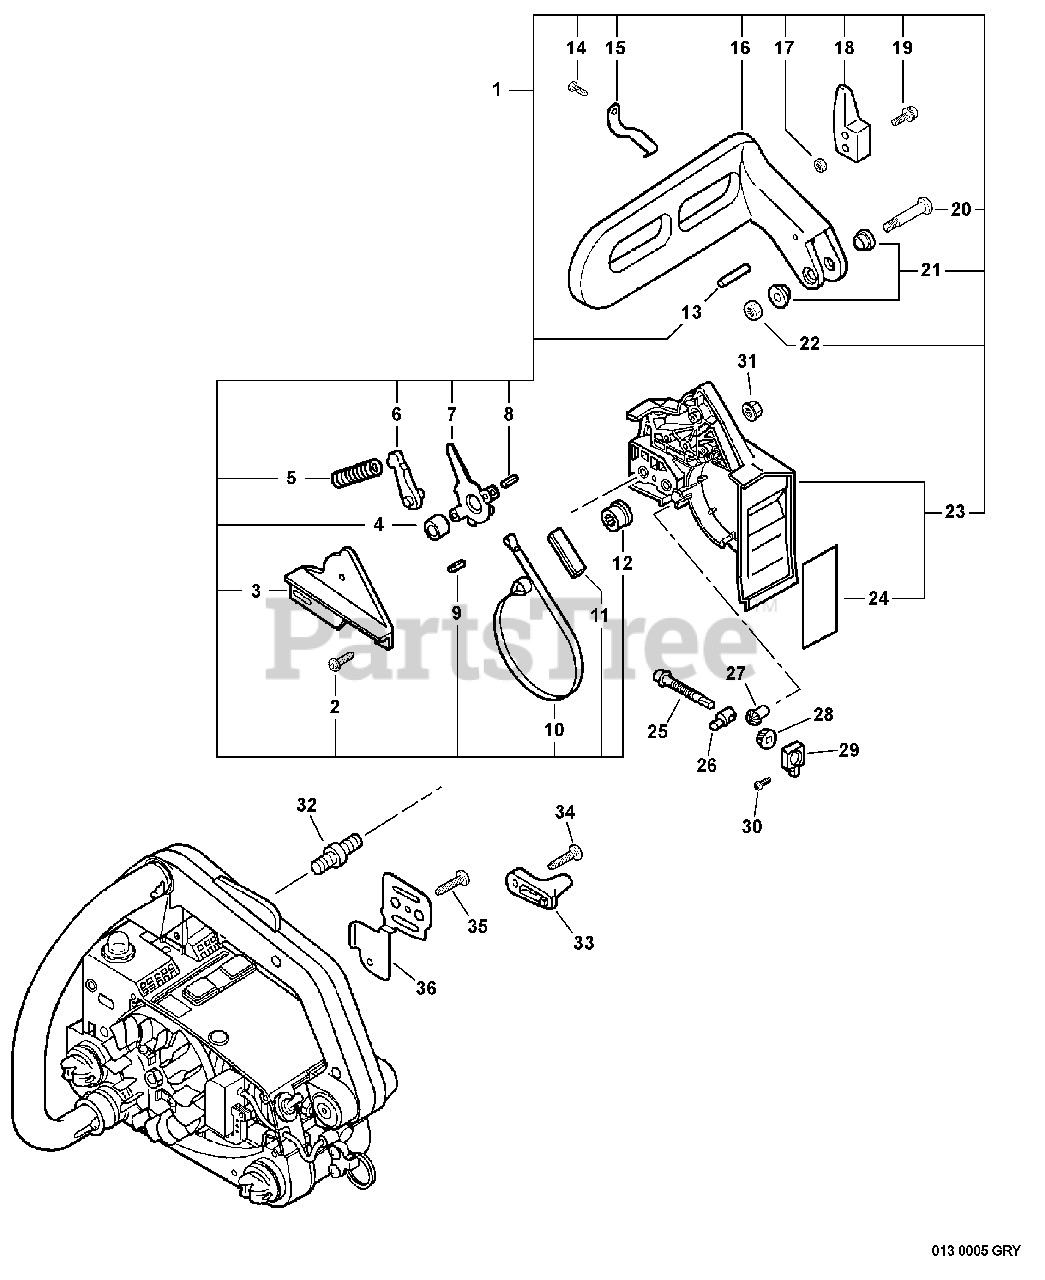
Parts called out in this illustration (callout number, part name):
1	CHAIN BRAKE ASSY
2	SCREW 4×12
3	COVER, BRAKE
4	SPACER 8×12×9
5	SPRING, COMPRESSION
6	STOPPER, BRAKE
7	LEVER, BRAKE
8	PIN, SPRING 4×8.8
9	PIN, SPRING 2.5×12
10	BAND, BRAKE
11	SEAL, BRAKE
12	ADJUSTER, BRAKE
13	ROLLER 4×23.8
14	SCREW 4×12
15	SPRING, FLAT
16	LEVER, BRAKE
18	WEIGHT, BRAKE
19	SCREW 4×22
20	SCREW 5×32
21	COLLAR 5.3×10×13×L5
22	NUT, LOCK M5
23	GUARD, SPROCKET - GRAY
24	SHIELD, HEAT 35×60×0.10
26	TENSIONER, CHAIN
27	GEAR, BEVEL
28	GEAR, BEVEL
29	COLLAR 8
30	SCREW 4×12
31	NUT, FLANGE M6
32	BOLT, STUD 6
33	CHAIN CATCHER
34	SCREW, TAPPING 5×20
35	SCREW 4×10
36	PLATE, GUIDE
